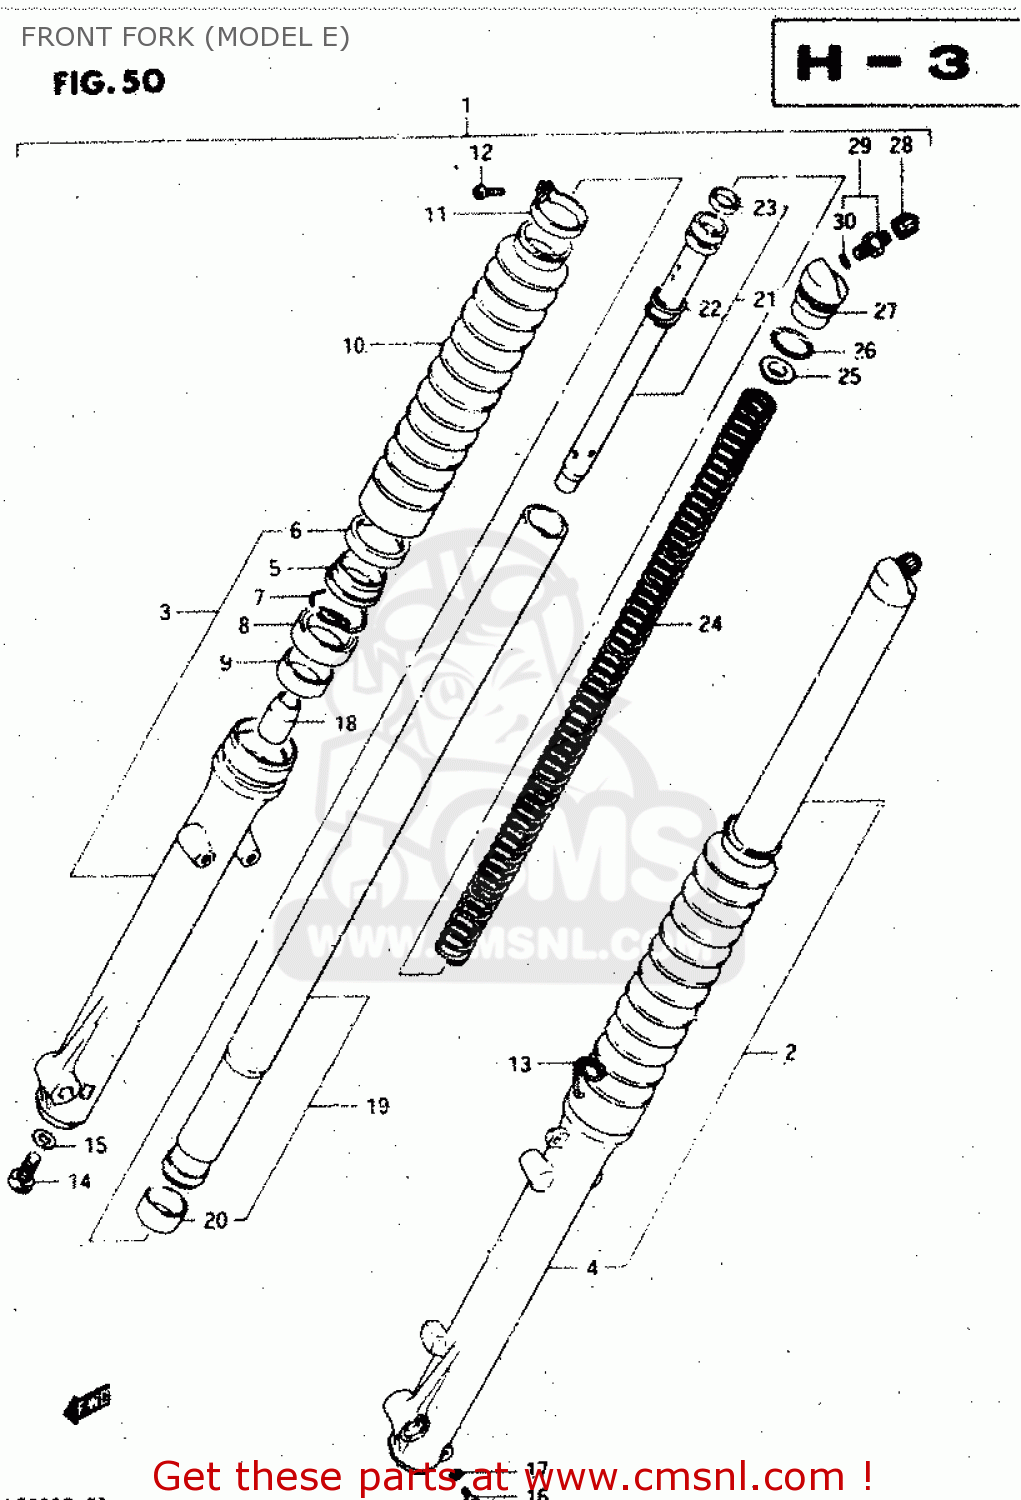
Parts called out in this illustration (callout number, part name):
1	DAMPER ASSY, RH (BLUE)
2	DAMPER ASSY, LH (BLUE)
3	OUTER TUBE RH
4	OUTER TUBE LH
5	SEAL,DUST
6	CASE,DUST SEAL
7	8
8	OIL SEAL,FRONT FORK
9	METAL,FRONT FORK SLIDE
10	BOOT (BLUE)
11	BAND,BOOT
12	SCREW
13	BAND,FRONT FORK COVER
14	BOLT,FORK CYLINDER(10X25)
15	GASKET (NAS)
16	SCREW
17	GASKET,DRAIN,PLUG (NAS)
18	PIECE,OIL LOCK
19	TUBE,FORK,INNER
20	PISTON
21	CYLINDER,FRONT FORK
22	SPRING
23	RING,FRONT FORK PISTON
24	SPRING,FRONT FORK
25	GUIDE,FRONT FORK SPRING C
26	O RING
27	BOLT,FORK
28	CAP
29	VALVE
30	O-RING
